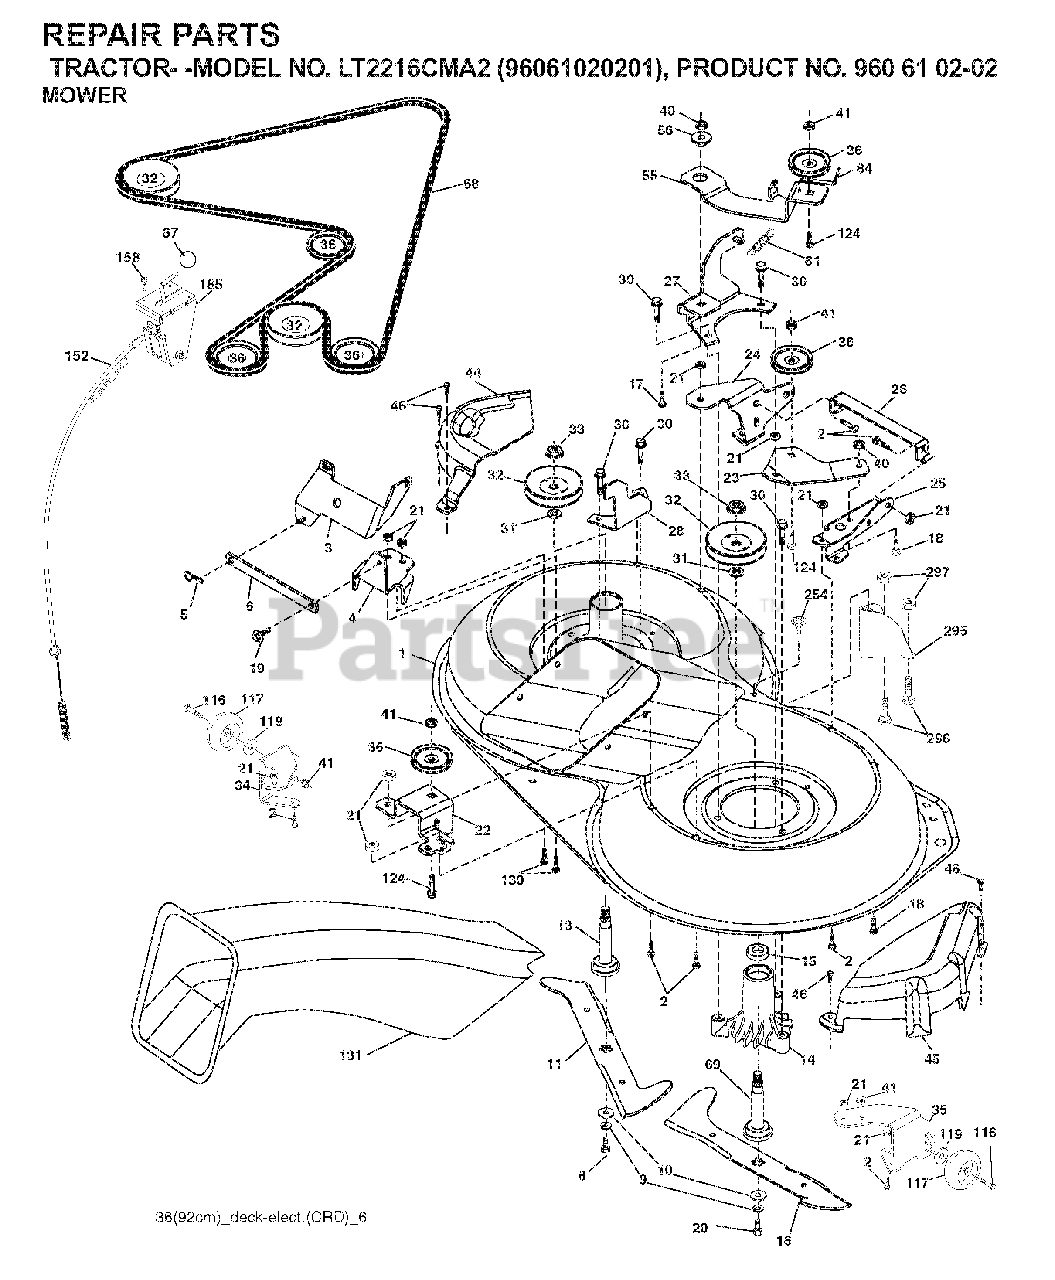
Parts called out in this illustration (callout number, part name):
2	BOLT
3	BRACKET
5	RETAINER-SPRNG RB
6	BAR SWAY
9	LOCKWASHER
10	WASHER.BLADE
13	SHAFT ASM VENT
14	HSG MANDREL
17	BOLT.3/8-14X1.25
18	BOLT
19	BOLT SHD 5/16-18
21	LOCKNUT
24	BRACKET
25	BRACKET
28	BRACKET
30	SCREW, WASHER HEAD
31	WASHER.SPACER.MANDREL
32	PULLEY MANDREL
33	NUT.FLANGE.LOCK.TOP
36	PULLEY.IDLER.4.25
40	LOCKNUT
41	NUT LOCK FLG 3/8-16 UNC
45	MANDREL COVER
46	SCREW.1/4-20X5/8
56	SPACER.RETAINER.MOWER
67	KNOB T (3/8 HOLE)
69	SHAFT.ASM.W/LWR.BRG.RH.THREAD
84	KEEPER, BELT IDLER
116	BOLT.SHOULDER.3/8-16X3-5/8
117	WHEEL. GUAGE RALLY
124	BOLT.3/8-16X1.50
131	CHUTE BAGGER
158	SCREW
185	HEAD ASM. CABLE CLUTCH
254	SCREW 3/8-16X1
296	BOLT
297	NUT CENTERLOCK
